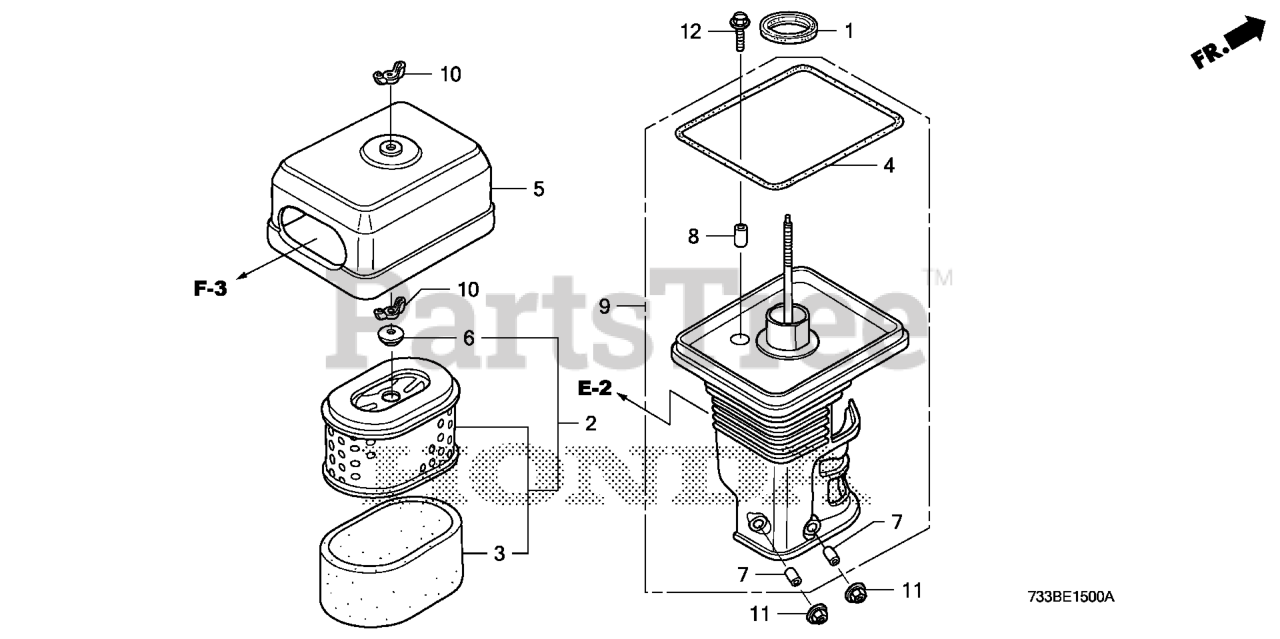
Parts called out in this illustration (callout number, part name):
1	GASKET, ELBOW
2	ELEMENT, AIR CLEANER
3	FILTER (OUTER)
4	GASKET, AIR CLEANER COVER
5	COVER, AIR CLEANER
6	GROMMET, AIR CLEANER
7	COLLAR, AIR CLEANER (ZHEJIANG HENGBO)
8	COLLAR B, AIR CLEANER
9	ELBOW, AIR CLEANER
10	NUT, TOOL BOX SETTING (ZHEJIANG HENGBO)
11	NUT, FLANGE (6MM)
12	BOLT, FLANGE (6X20)
